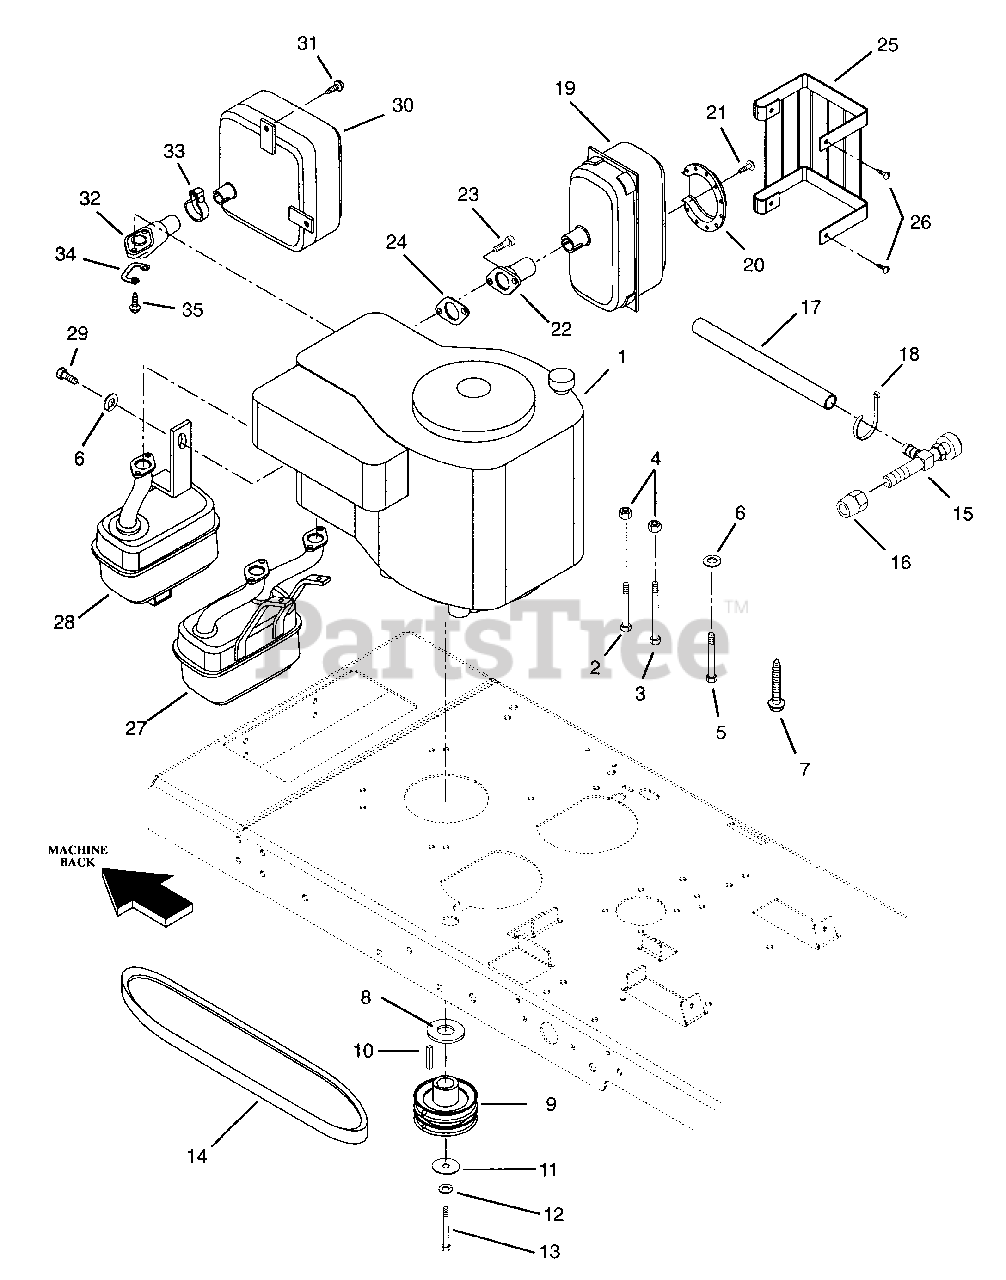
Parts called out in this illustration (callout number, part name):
1	ENGINE- 14.0 B&S VANGUARD SING
1	ENG- 15.0 KOHLER OHV PS-41531
1	ENGINE- 16.0 TEC OHV
1	ENGINE- 16.0 B&S VANGUARD TWIN
2	BLT-HEX .31-18X1.25 PL GR5
3	BLT-HEX .31-18X1.50 PL GR5
4	NUT-LK .312-18 GR A PL
5	BLT-HEX M8 X 1.25X25 PL GR5
6	WSHR-LK .313X.078 PL MED
7	SCR-TAP .375-16X1.25 HWH PL TR
8	WSHR-FL-STL 1.062X2.000X.134
9	PLY 3.75 W/1.00 ID AND KEYWAY
10	KEY-SQ .25 X 2.50 X .25 SAE
11	WSHR-SPECIAL .469X2.000X.250
12	WSHR-LK .438X.133 HVY
13	BLT-HEX .44-20X1.25 GR5
14	V-BELT, 3L-RAW EDGE
15	COCK, OIL DRAIN
16	ADAPTER, OIL DRAIN
17	TUBE OIL DRAIN
18	CABLE TIE LG 5-1/2
19	MUFFLER B&S
20	DEFLECTOR B+S 222573
21	SCREW B+S 93705
22	MUFFLER ADAPT. PIPE B+S 496656
23	SCR-CAP .31-18X.75 S/HD
24	GASKET B&S#272293
25	GUARD, MUFFLER
26	SCR-TAP .250-20X.37 HWH PL TR
27	MUFFLER ASSY.
27	MUFFLER SHIELD
28	MUFFLER, KOHLER
29	BLT-HEX .31-18X.50 GR5
30	MUFFLER ASSY.
31	SCR-TAP .25-20X.50 HWHPL
32	MANIFOLD-EXHAUST
33	CLAMP, MUFFLER
34	PLATE, LOCK
35	SCREW SPECIAL (MANIFOLD)
